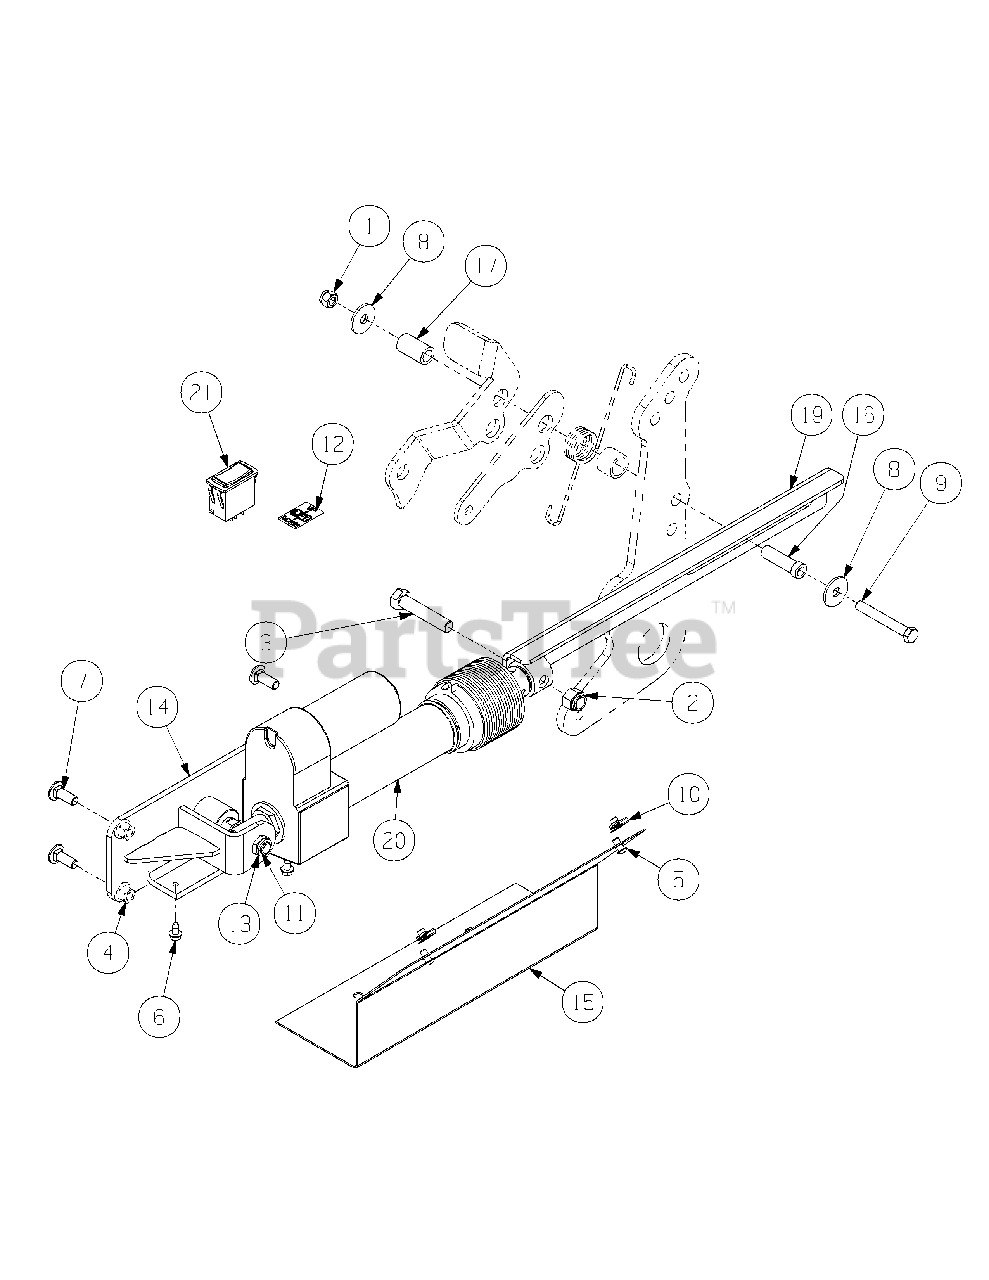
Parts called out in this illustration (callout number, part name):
1	Nut, 3/8-16, Nylock
2	Nut, 1/2-13, nylock
3	HHCS, 1/2-20 x 2.50
4	Nut, 3/8-16, Flangelock
5	Capscrew, 1/4-20 x .500
6	Self Tapping Screw, 1/4-20 x .50
7	Carriage Bolt, 3/8-16 x 1.00
8	Washer, 1.25 x .411 x .100
9	HHCS, 3/8-16 x 2.75
10	U-Nut, 1/4-20
11	Pivot Pin
12	Label, Up/Down
13	Jam Nut, 1/2-13
17	Spacer, .515 ID x .75 OD x 1.313
21	Switch
